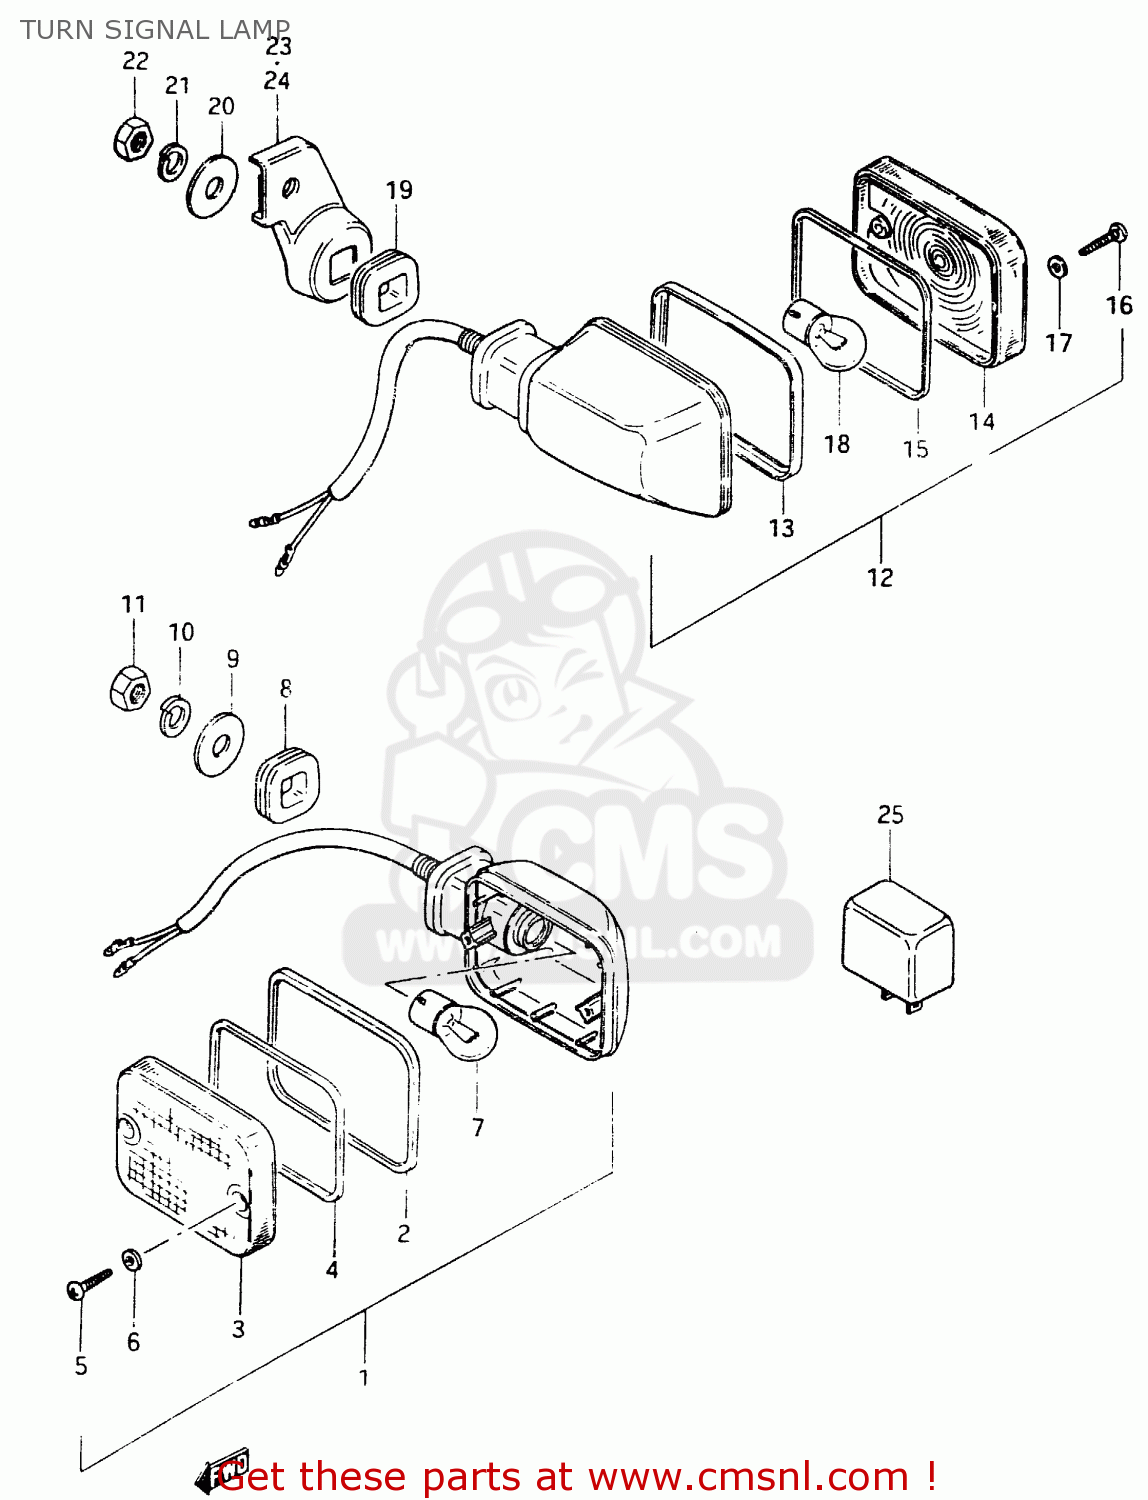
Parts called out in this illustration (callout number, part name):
1	LAMP ASSEMBLY,FRONT TURN SIGNAL
2	RIM
3	LENS
4	GASKET (NAS)
5	SCREW
6	GASKET (NAS)
7	BULB(12V23W,STANLEY,A4577A)
8	CUSHION
9	WASHER (10.5X30X2.3)
10	LOCK WASHER
11	NUT
12	LAMP ASSEMBLY,FRONT TURN SIGNAL
13	RIM
14	LENS
15	GASKET (NAS)
16	SCREW
17	GASKET (NAS)
18	BULB(12V23W,STANLEY,A4577A)
19	CUSHION
20	WASHER (10.5X30X2.3)
21	LOCK WASHER
22	NUT
23	BRACKET,REAR TURN SIGNAL
24	BRACKET,REAR TURN SIGNAL
25	RELAY,TURN SIGNAL
